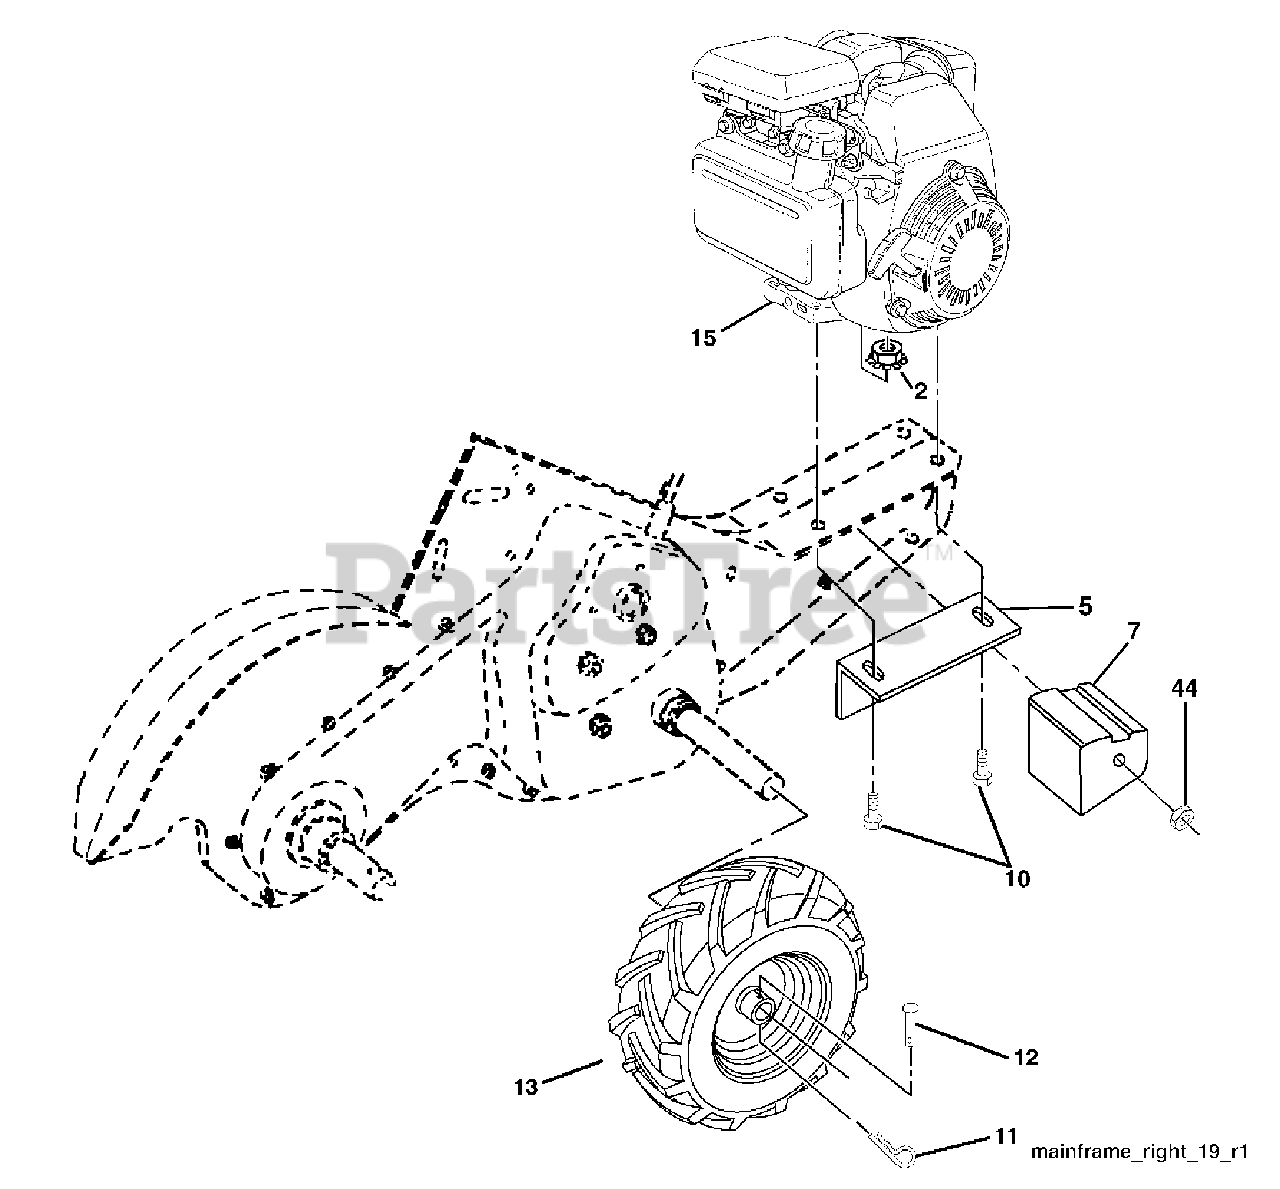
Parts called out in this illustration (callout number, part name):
2	Locknut, Hex, Flange 5/16-18
5	Bracket, Reinforcement
7	Counter Weight, R.H.
10	Bolt, Hex 5/16-18 x 1-1/2
11	Clip, Hairpin
12	Rivet, Drilled
15	Engine, Honda Model No. GCL160LA QHA2 (Order parts from engine manufacturer)
44	Nut Keps Hex 3/8-16 unc
